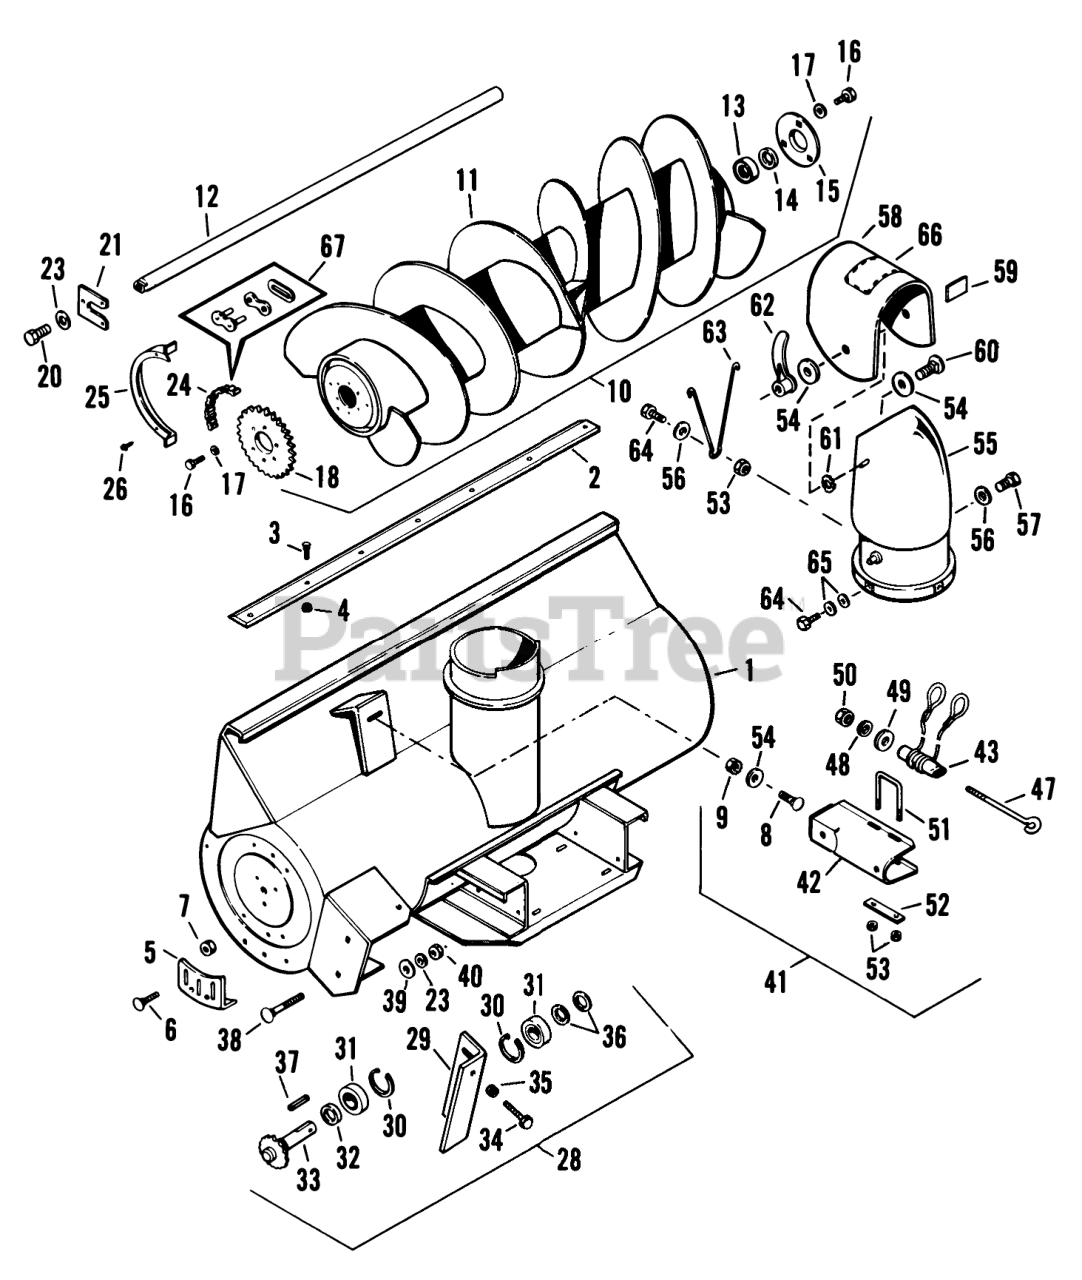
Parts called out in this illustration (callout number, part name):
1	Assy.-Header Hsg. 48"
2	Blade-Scraper
3	BOLT-BLADE TO HEADER
4	Nut 1/4-20 Keps
5	Shoe-Skid
6	Bolt-5/16-18 x 3/4 Carr.
7	Nut 5/16-18 Keps
8	Bolt 3/8-16 x 1
9	Nut, Jam, 3/8-24 Thd
10	Auger Assembly
11	Auger
12	Hex Nut
13	Bearing-Auger
14	Washer-Auger
15	Spring
16	Bolt Hex 5/16-18
17	Lockwasher
18	Control Rod-Traction
20	Bolt Hex 1/2-13 x 1 1/4
21	PLATE AUGER MOUNTING
23	Lockwasher
24	CHAIN-AUGER DRIVE
25	Chain Guard
26	Screw-1/4-14 x 1/2 Hex. Self Tap
28	Jackshaft Housing w/Bearings
29	Assy.-Jackshaft Hsg.
30	Ring-Snap
31	BEARING-GEAR BOX
32	Spacer
33	Jackshaft and Sprocket
34	S.T. Bolt 5/16-18 x 2
35	Nut 5/16-18 Jam
36	WSHR SPROCKET TO BRG
38	Bolt-1/2-13 x 3-1/2 Carr.
39	Washer 7/16
40	Nut, 1/2-13
41	Stack Drive Bracket
42	Assy.-Stack Drive Brkt.
43	ASSEMBLY CABLE
47	EYE BOLT DRIVE TUBE
48	Spring Washer
49	Washer
50	3/8-16 E.S.
51	U-BOLT
52	Friction Strap
54	WASHER
55	Assy.-Elbow & Pivot
56	Washer
57	Bolt, 1/4-x 1/2
58	Deflector Elbow
59	MOLDING DEFLECTOR
60	Bolt-Car. 5/16-18 x 1
61	Washer
62	STRAP-LOCKING
63	Spring Hook
64	Bolt-1/4-20 x 5/8
65	Washer-1/4 Med. Lock
66	Caution Decal
